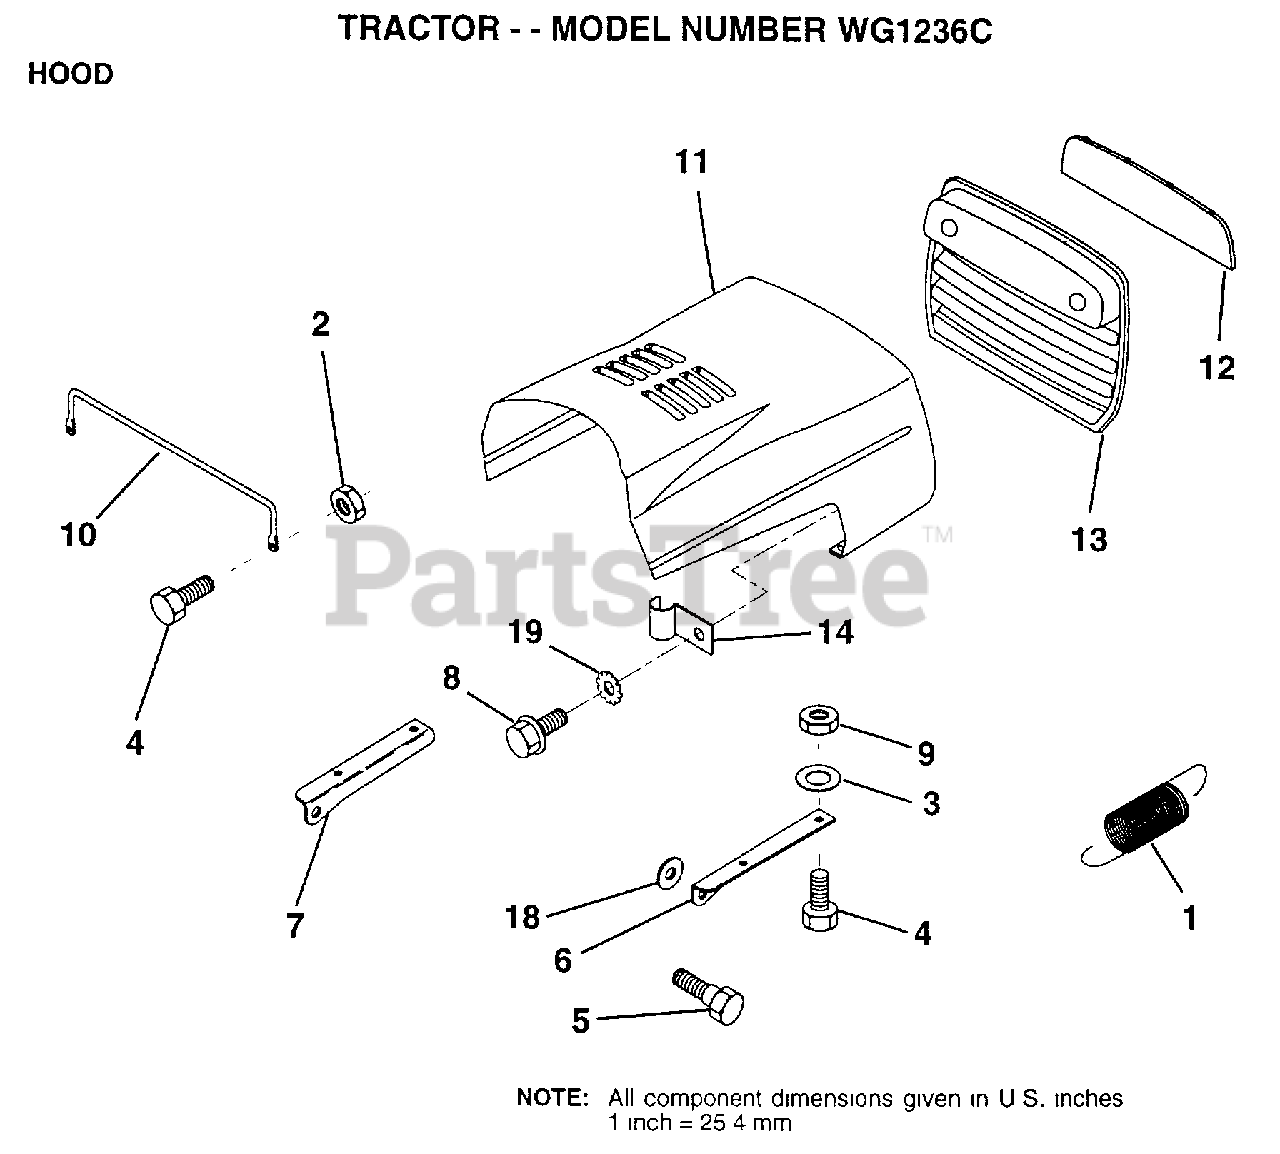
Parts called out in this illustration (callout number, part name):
1	EXT SPRING
2	NUT HXKEP 1/4X20
3	WASHER
5	BOLT.SHLD.5/16-18
6	BRKT HOOD RH
7	BRKT HOOD LH
8	SCREW SLTD HXHD
9	NUT
10	"BRACE,HOOD"
11	HOOD.IMPREG.MS550
12	LENS
13	GRILL
14	CLIP T
18	WASHER
19	LOCKWASHER GT
